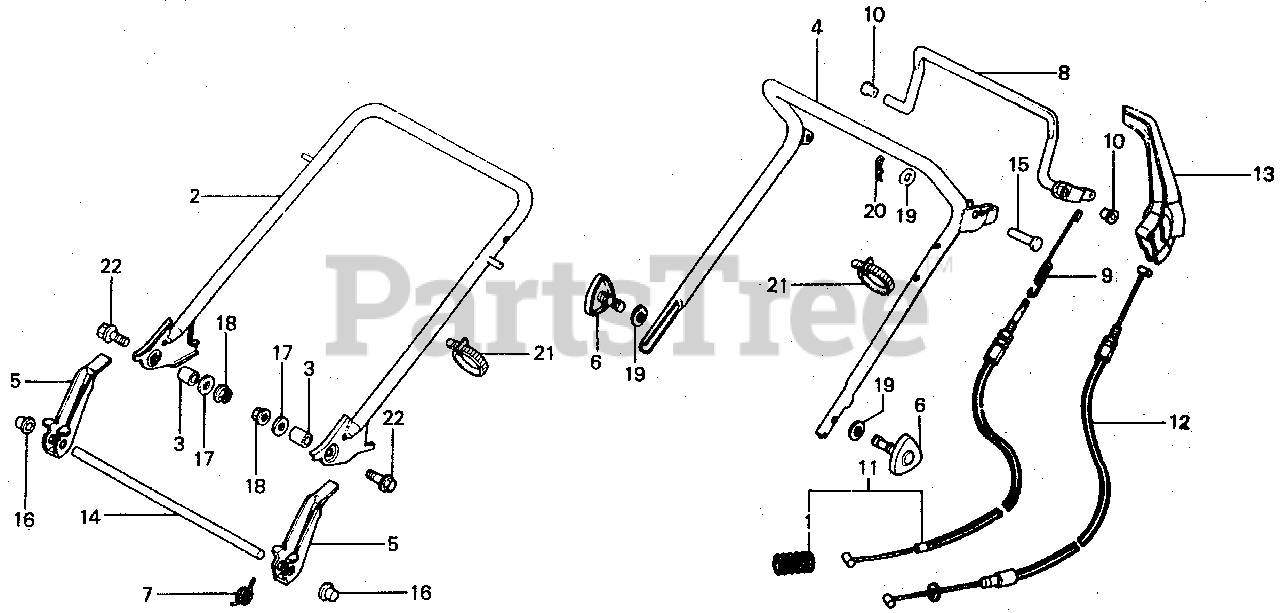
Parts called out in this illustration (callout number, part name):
1	SPRING, CLUTCH RETURN
2	HANDLEBAR (LOWER)
3	COLLAR (LOWER)
4	PIPE (UPPER) (NOT AVAILABLE)
5	LEVER, LOCK
6	GRIP, HANDLE JOINT
7	SPRING, HANDLE
8	LEVER, CLUTCH
9	SPRING, CLUTCH (NOT AVAILABLE)
10	BUSH, CLUTCH LEVER
11	CABLE A, CLUTCH
12	CABLE, ROTO-STOP CLUTCH
13	LEVER, ROTO-STOP CLUTCH
14	SHAFT, SHIELD
15	PIN, CLUTCH LEVER (NOT AVAILABLE)
17	WASHER (8MM)
18	NUT, FLANGE (8MM)
19	WASHER, PLAIN (8MM)
20	PIN, LOCK (8MM)
21	BAND B1, CABLE
21	BAND B2, CABLE HARNESS
22	BOLT, FLANGE (8X32)
